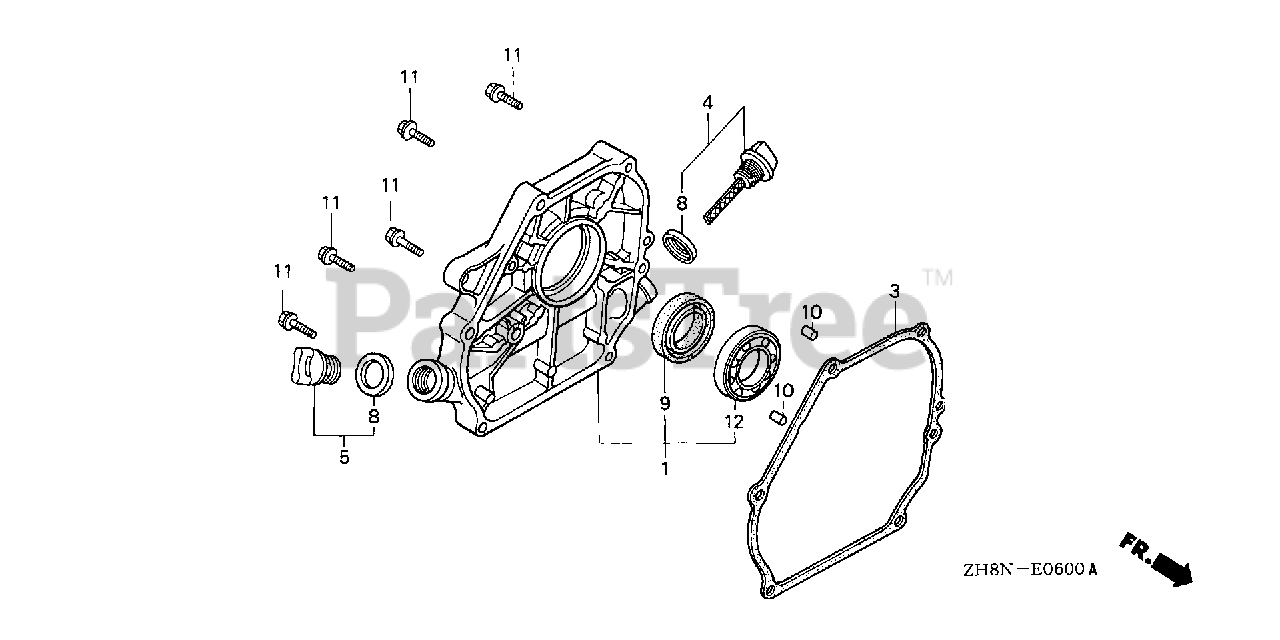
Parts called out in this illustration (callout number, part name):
1	COVER ASSY., CRANKCASE (U-TYPE)
3	GASKET, CASE COVER (NON-ASBESTOS)
4	CAP ASSY., OIL FILLER
5	CAP ASSY., OIL FILLER
8	GASKET, OIL FILLER CAP
9	OIL SEAL (25X41X6)
10	PIN A, DOWEL (8X14)
11	BOLT, FLANGE (8X32)
12	BEARING, RADIAL BALL (6205)
